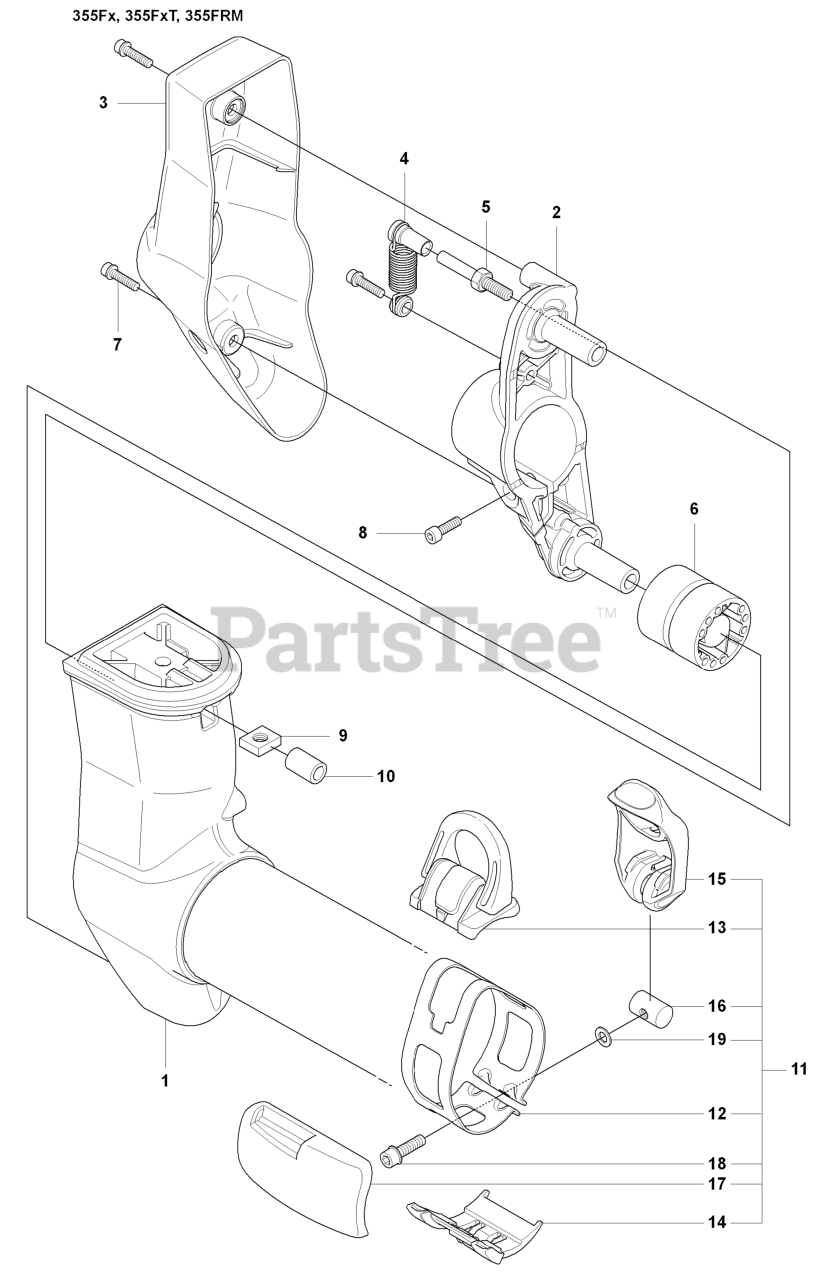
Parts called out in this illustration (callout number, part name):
1	SUSPENSION
4	SPRING
5	PARALLEL PIN
6	ANTIVIBE ELEMENT
7	SCREW IHSCFM
11	LOOP
14	GUIDE RAIL
17	WEAR PROTECTION
19	WASHER 5.3X12
